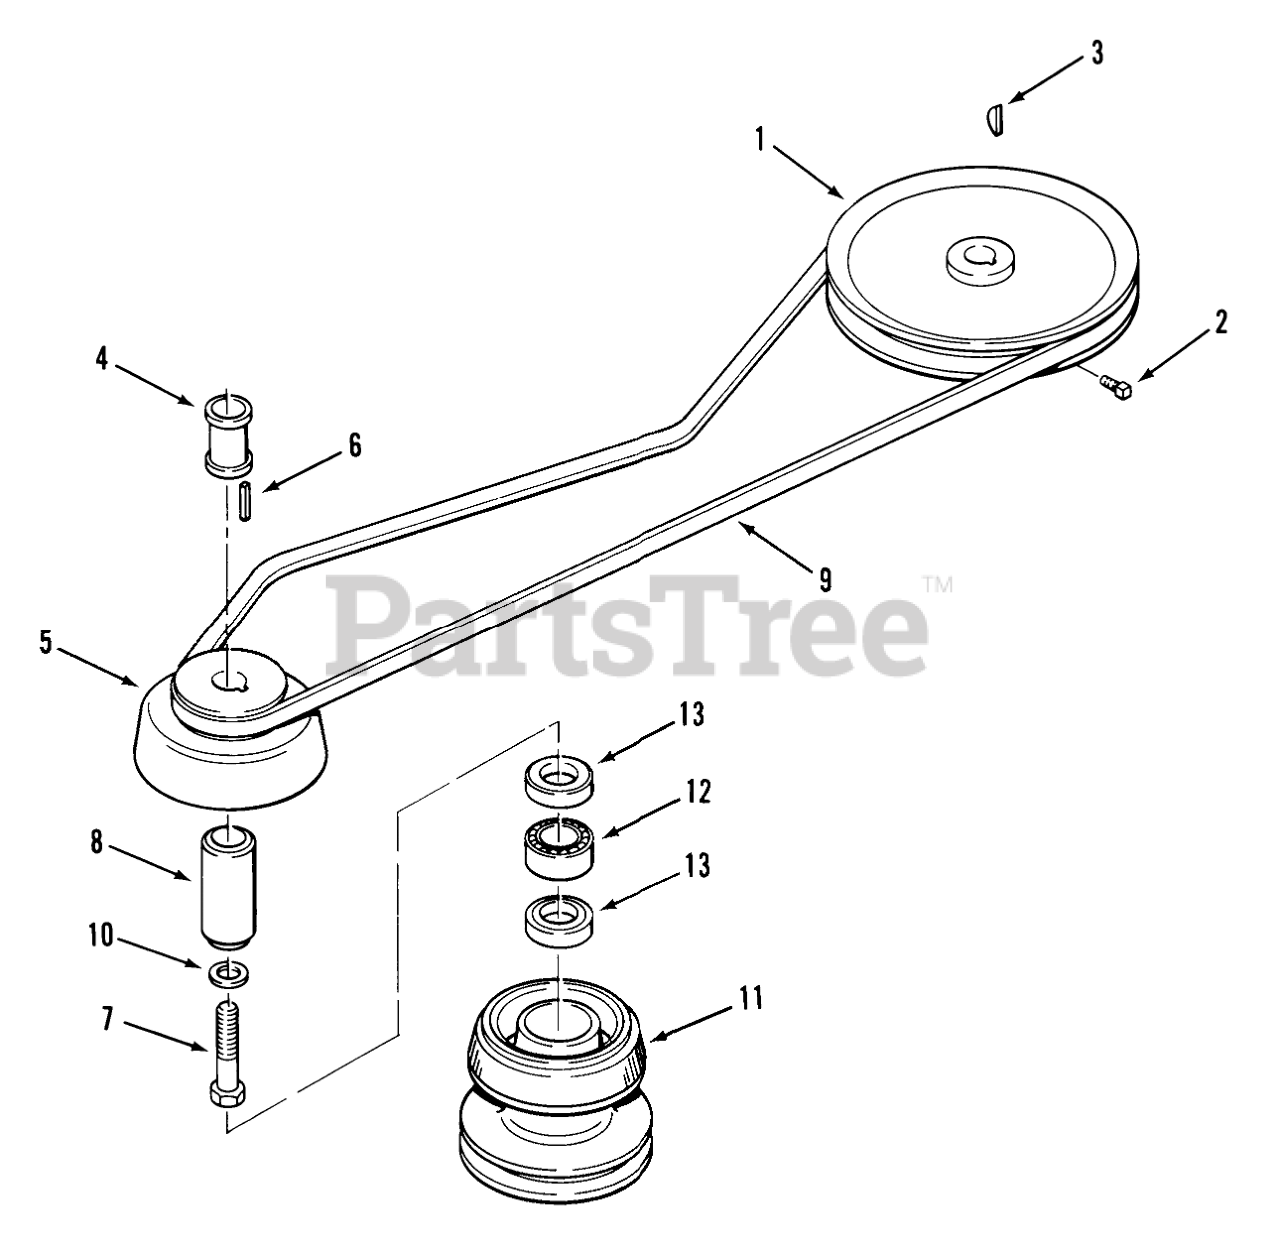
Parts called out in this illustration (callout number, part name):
1	PULLEY-TRANSMISSION
2	Set Screw
3	HARD HI PRO KEY
4	TUBE SPACER
5	PULLEY-ENGINE
7	HEX HD CAP SCREW
8	RACE BEARING
9	V-BELT
10	WASHER
11	Assy Pulley Mwr Dr
12	BRG-NEEDLE OPEN END
13	SEAL-OIL
